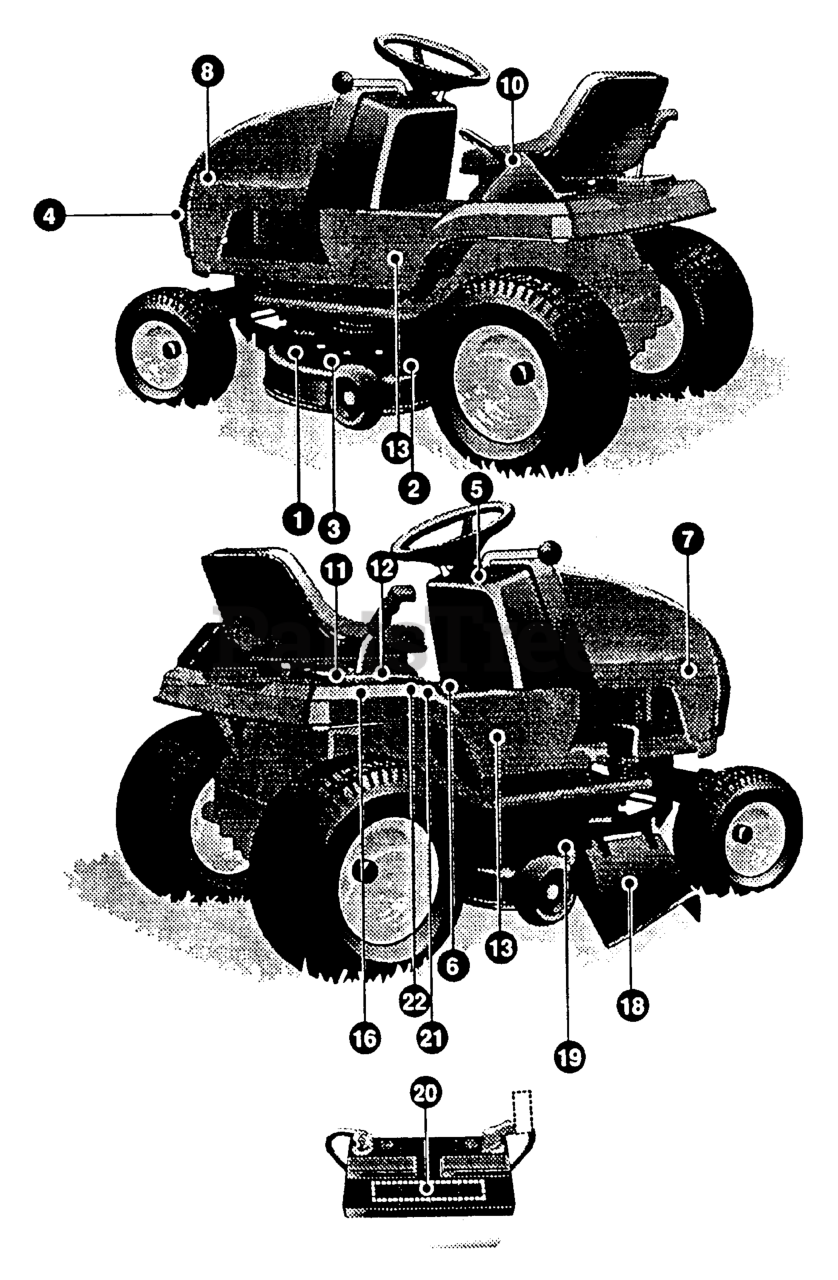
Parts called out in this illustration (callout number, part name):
2	DECAL, K-MART TURBO
3	DECAL, K-MART CUT MULCH
4	DECAL, K-GRO OVAL
5	DECAL, DASH, H24/H25
6	DECAL, CAUTION CONSOLE TOP
7	DECAL, POWER PRO 14.5 HOOD
8	DECAL, POWER PRO 14.5 HOOD
10	DECAL, HEIGHT ADJUST
11	DECAL, SHIFT REVERSE/NEUTRAL
12	DECAL, SHIFTER POSITION
13	DECAL, K-MART 43" CONSOLE
16	DECAL, K-MART QUICK SHIFT
18	DECAL, MULCHING KIT INSTALLED
20	DECAL, BATTERY INSTRUCT FRE/ENG
